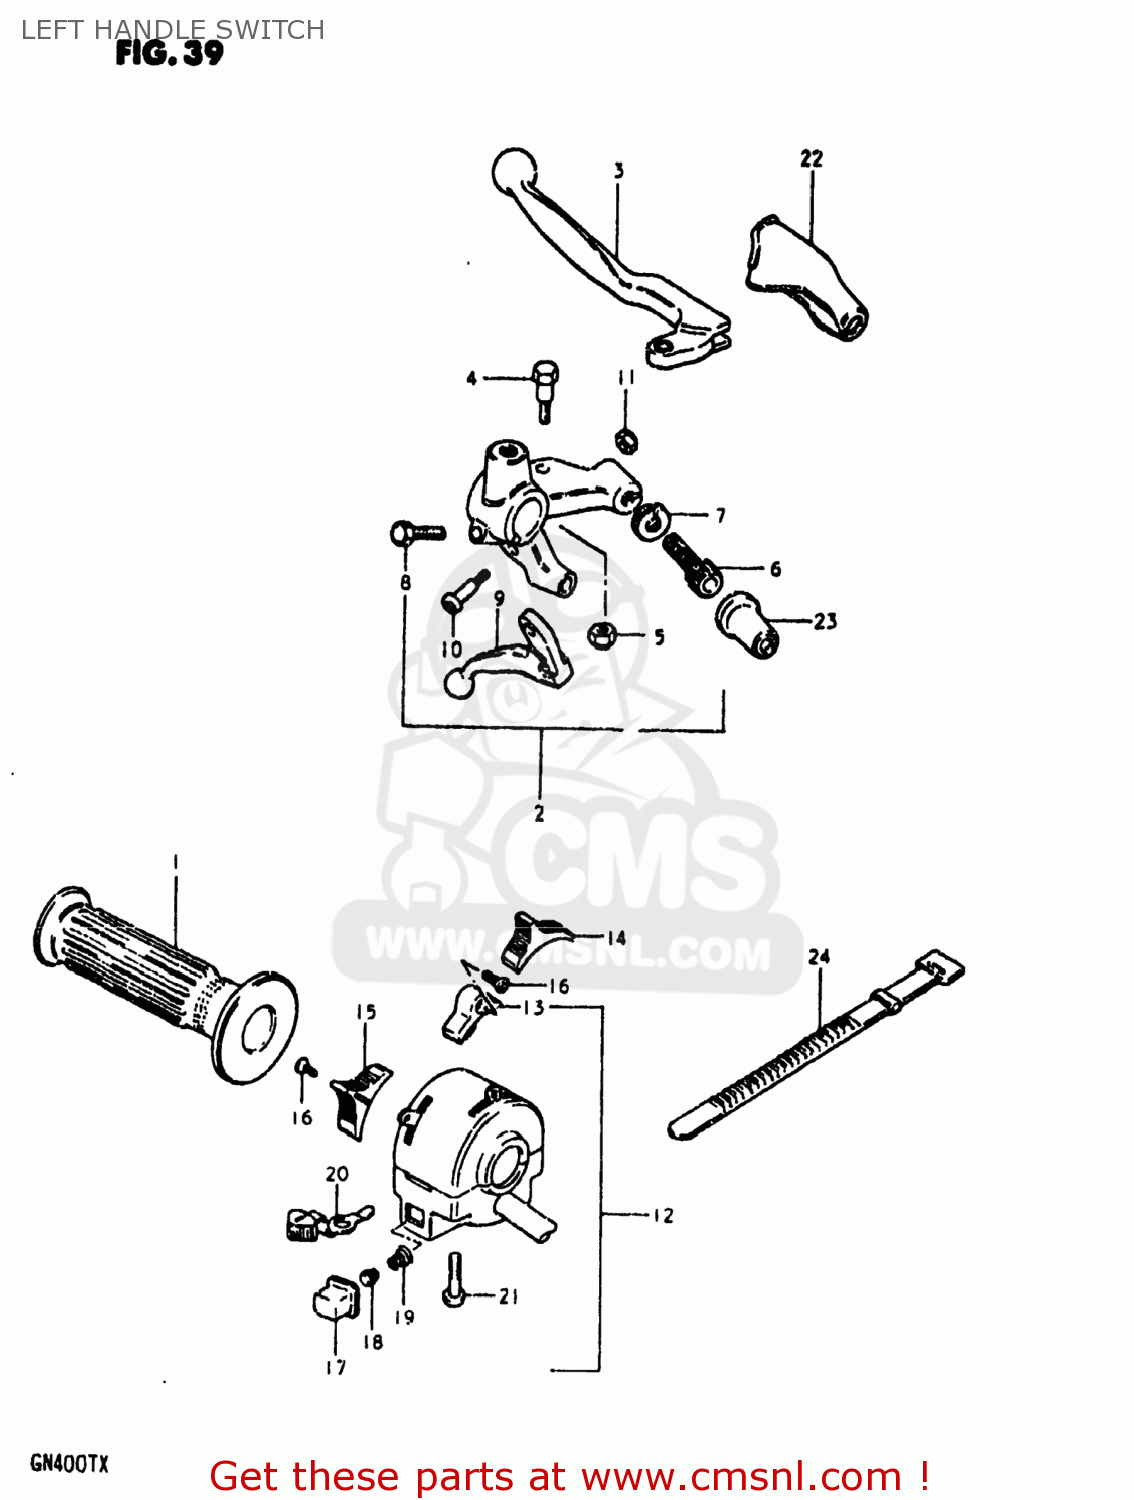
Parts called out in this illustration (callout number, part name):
1	GRIP,L
2	LEVER ASSEMBLY,CLUTCH/DECOMPRESSION
3	LEVER,CLUTCH
4	BOLT,LEVER
5	NUT 6MM
6	ADJUSTER,CABLE
7	NUT,CABLE ADJUSTER
8	BOLT
9	LEVER,DECOMPRESSION
10	BOLT,LEVER
11	NUT,LEVER BOLT
12	SWITCH ASSEMBLY,HANDLE,LEFT
13	KNOB,STOP
14	KNOB,LIGHTING SWITCH
15	KNOB,DIMMER SWITCH
16	SCREW
17	BUTTON,HORN
18	CONTACT
19	SPRING
20	KNOB,TURNSIGNAL
21	SCREW
22	COVER,CLUTCH LEVER
23	BOOT,CLUTCH CABLE
24	CLAMP(L:120)
